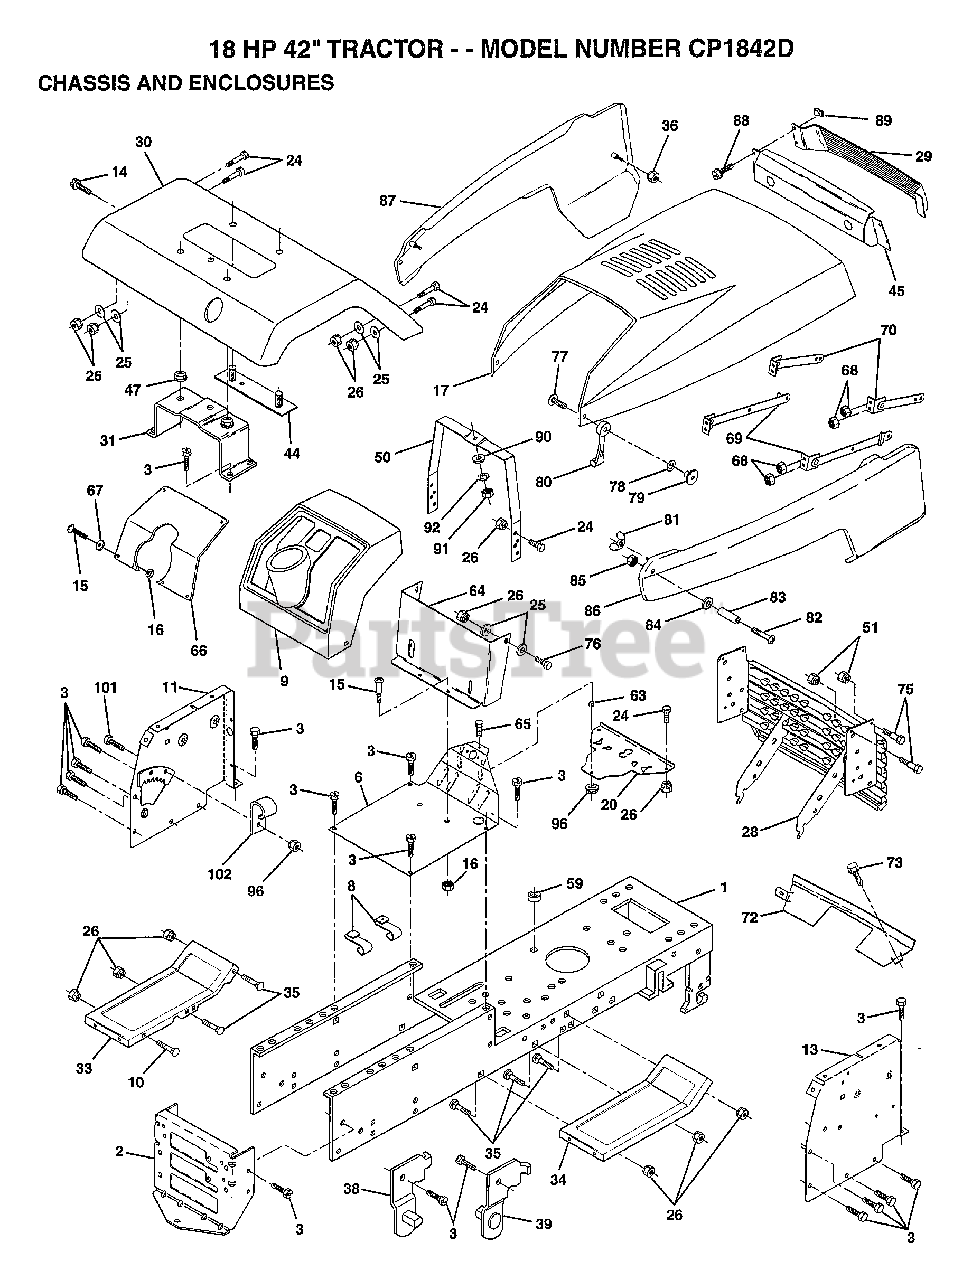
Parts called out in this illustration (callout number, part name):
3	SCREW
8	"CLIP,INSULATOR"
9	DASHBOARD BLACK
11	PANEL.DASH.LH.ASM
13	PANEL.DASH.RH.ASM
14	SCREW LT
15	SCREW
20	PLATE.SUPT.BATTER
24	BOLT
25	WASHER
26	NUT
29	LENS LT
31	BRKT.ASM.FENDER
35	BOLT
36	PAL NUT LT
38	BRACKET ASM LH
39	BRACKET ASM RH
44	STRAP ASM FENDER
47	NUT-PUSH YT
50	SUPPORT ASS'Y
63	SPACER
65	BOLT
66	PLATE.SILKSCREEN
67	WASHER
68	NUT
72	STRAP.GRILLE.PNT
73	SCREW CRT
76	BOLT
77	SCREW
78	LOCKWASHER
79	WELDNUT
80	HOOD LATCH T
82	SCREW
83	SPACER LT
84	WASHER
86	"PANEL, SIDE RH"
87	"PANEL,SIDE LH"
89	"""J"" FASTENER LT"
90	LOCKWASHER
92	WASHER PM
96	NUT
101	BOLT
102	CLIP T
